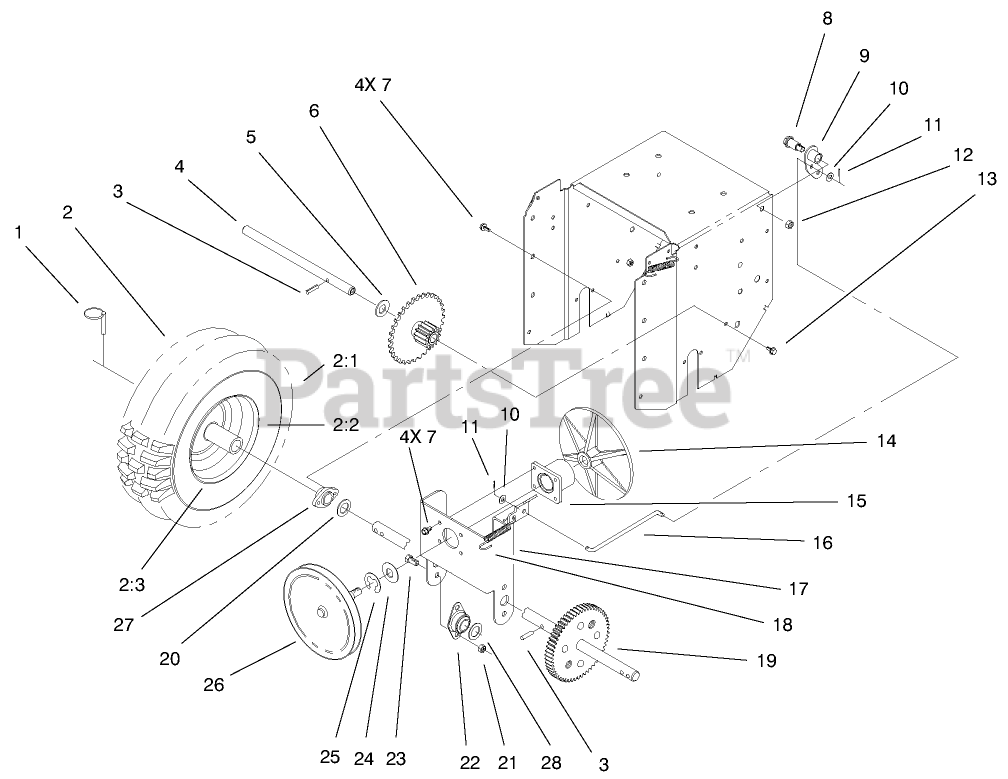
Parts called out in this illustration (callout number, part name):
1	PIN-LYNCH
2	ORDER SEPERATE COMPONENTS
2:2	TUBE-INNER
2:3	RIM-WHEEL
3	PIN-ROLL, SLOTTED
4	SHAFT - INTERMEDIATE
5	WASHER
6	GEAR/BUSHING ASM
7	SCREW-HWH
8	BOLT - SHOULDER
9	HUB-PIVOT
10	WASHER
11	PIN-COTTER
13	SCREW-HWHTF
14	DISC - FRICTION
16	ROD - ENGAGE
17	FRAME-FRICTION PLATE
20	WASHER-THRUST
21	NUT-LOCK, NI
22	BUSHING
23	SCREW-HH
24	WASHER-THRUST
25	RING-RETAINING, EXT
26	PULLEY/SHAFT ASM
27	BEARING-AXLE
28	WASHER-THRUST
